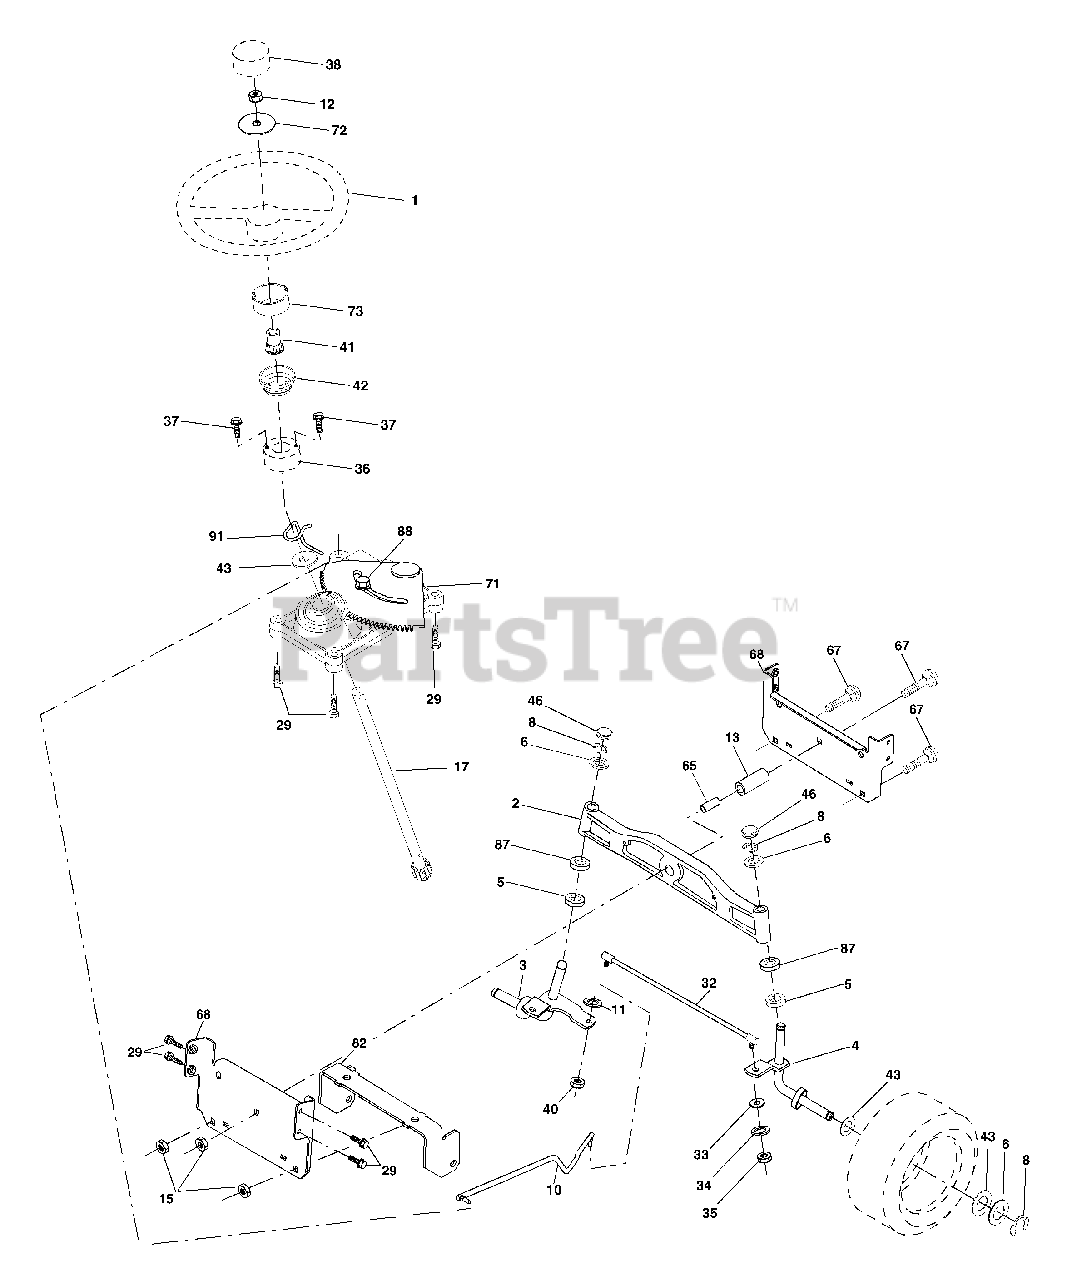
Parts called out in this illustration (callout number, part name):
1	Wheel Steering
2	Axle Cast Lt Machined
3	Spindle Asm LH
4	Spindle Asm RH
5	Bearing Race Thrust Harden
6	Washer 25/32 X 1-5/8 X 16 Ga
8	Ring Klip #t5304-75
10	Link Drag
11	Washer Lock Hvy Hlcl Spr 3/8
12	Nut Hex Jam Toplock 1/2-20 UNF
13	Spacer Brg Axle Front
15	Nut Hex Flange Lock
17	Shaft Asm Strg
29	Screw 3/8-16x3/4
32	Rod Tie
33	Washer 11/32 x 3/4 x 16 Ga.
34	Washer Lock Hry Hlcl Spr 5/16
35	Nut Crownlock 5/16 - 24 UNF
36	Bushing Strg
37	Screw TT #32.5 x 5 x 3/8 Flange
38	Cap Wheel Steer
40	Nut Lock Center 3/8-24 Unf
41	Adaptor Wheel Strg
42	Boot Steering
43	Washer 25/32 X 1 1/4 X 16 Ga
46	Cap Spindle Fr Top Blk
65	Spacer Brace Axle
67	Bolt Rdhd Sqn 3/8-16 x 2-1/4
68	Brace, Axle
71	Steering Asm.
72	Washer 9/16 ID x 1/20 OD 11 Ga.
73	Extension Steering
82	Bracket Susp Chassis Front
87	Washer Flat .781 x 1-1/2 x .14
88	Bolt Shoulder 7/16-20 Unc
91	Clip
